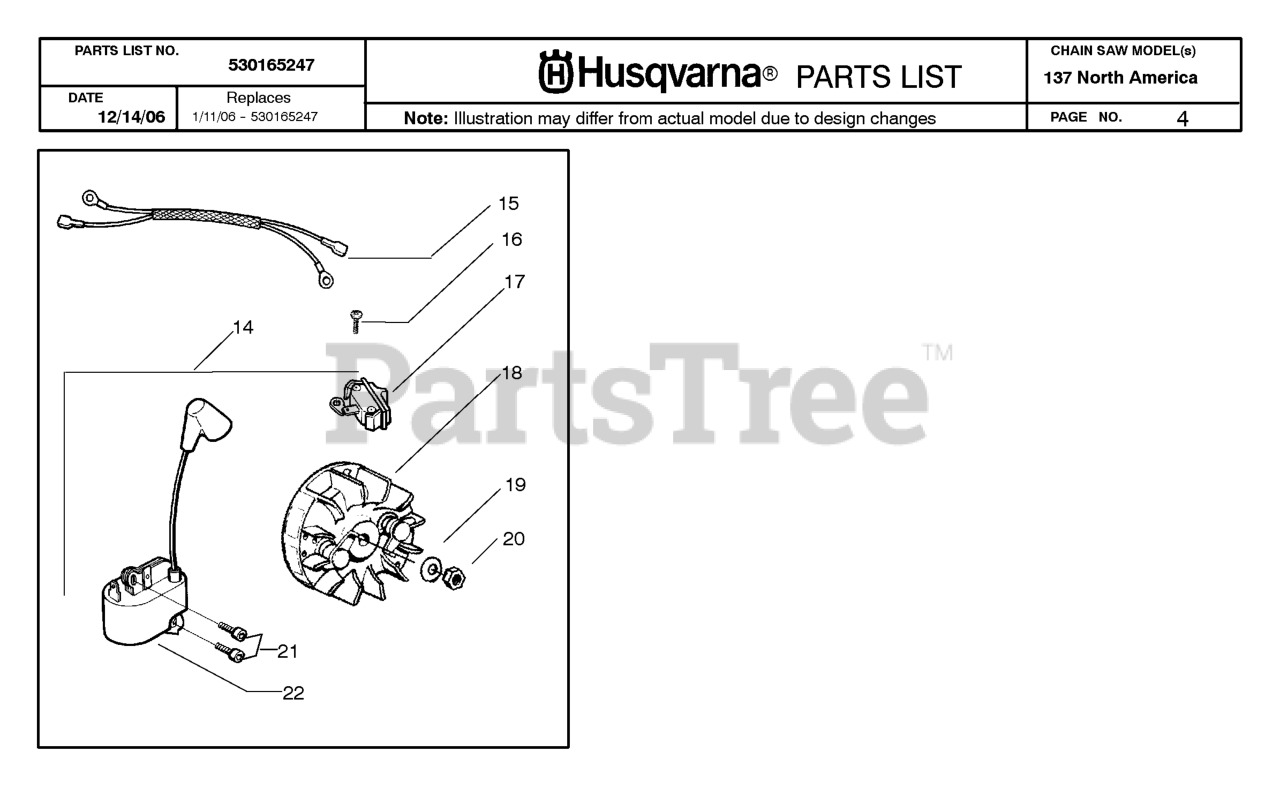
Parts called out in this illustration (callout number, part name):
14	KIT EPS IGNITION
15	LEAD WIRE ASSY
17	SWITCH ON/OFF
18	FLYWHEEL ASSY
19	WASHER-FLYWHEEL
20	NUT-FLYWHEEL
22	IGNITION MODULE
